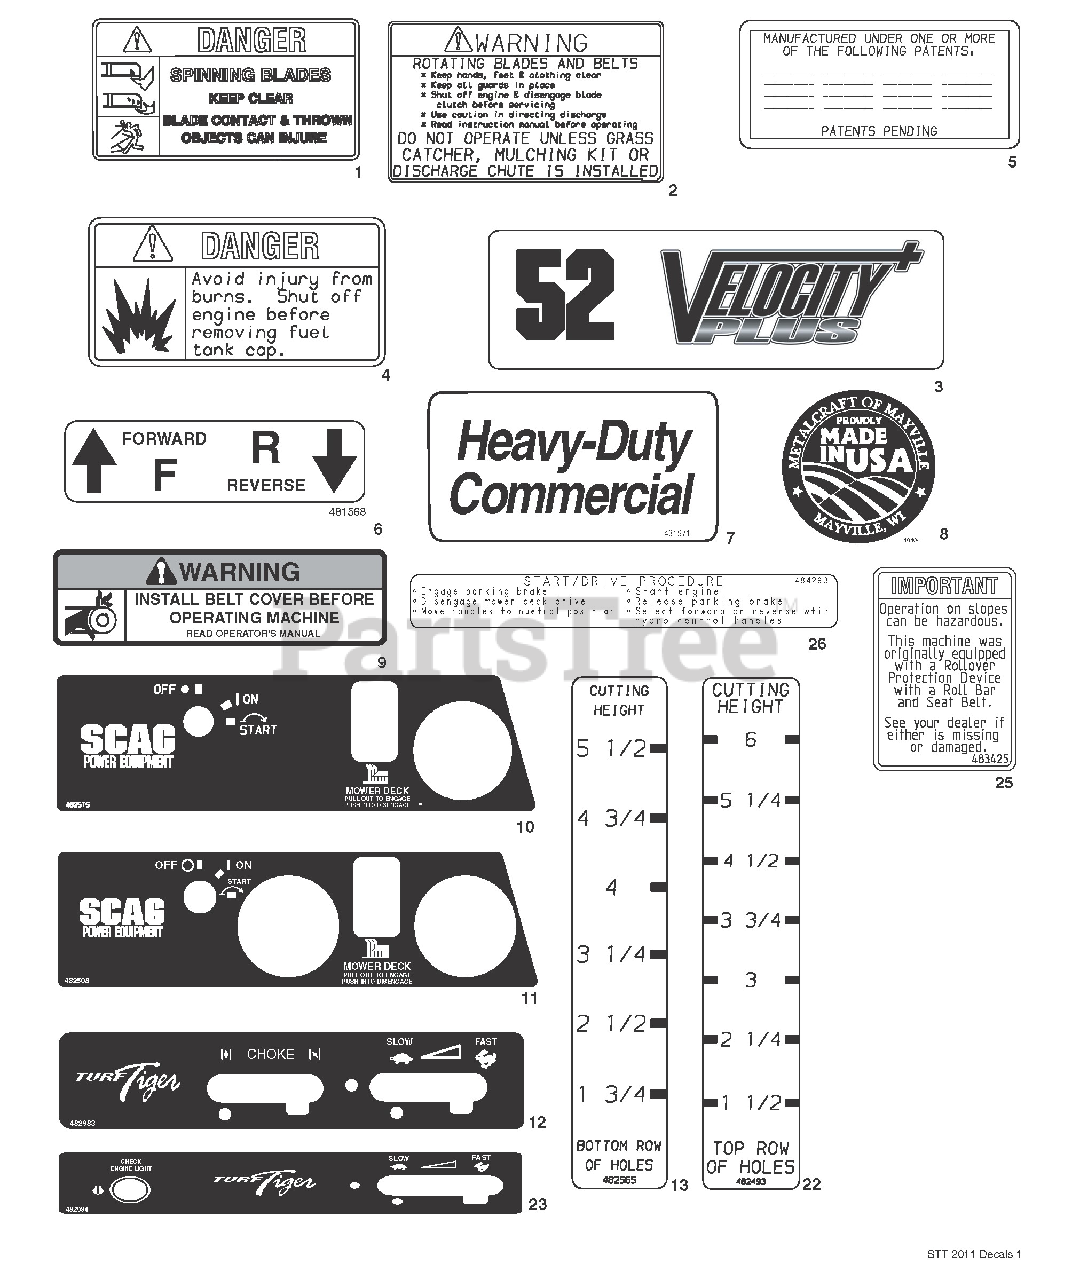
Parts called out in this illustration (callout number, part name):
1	Decal, Danger - Spinning Blades
2	Decal, Warning - Rotating Blades
3	Decal
4	Decal, Fuel Tank
5	Decal, Patents
6	Decal, Traction Control
7	Decal, Heavy-Duty Commercial
8	Decal, Metalcraft-Made In USA
9	Decal, Belt Cover
10	Decal, Instrument Panel - Upper
11	Decal, Instrument Panel - Upper
12	Decal, Instrument Panel-Lower
13	Decal, Cutting Height - Lower
22	Decal, Cutting Height - Upper
23	Decal, Instrument Panel - Lower
25	Decal, ROPS
26	Decal, Start / Drive
